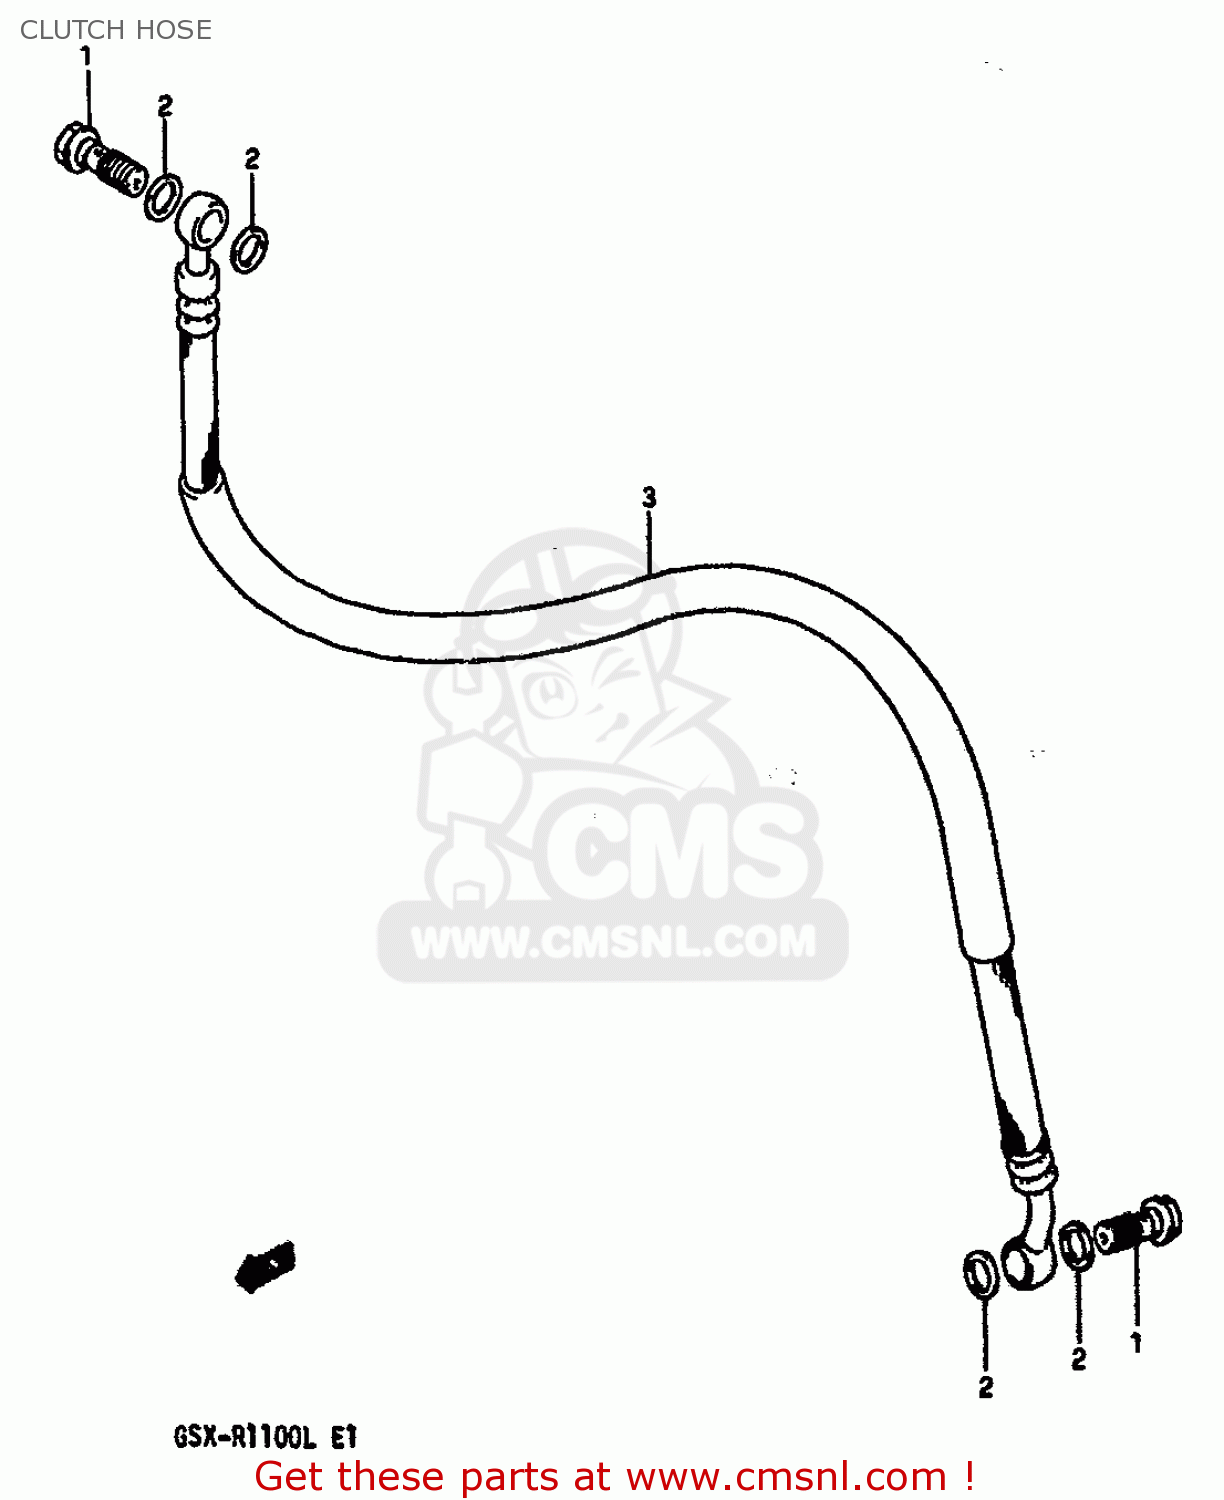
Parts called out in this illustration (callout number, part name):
1	BOLT UNION
2	WASHER(10X15X1.5)
3	HOSE,PROTECTOR
